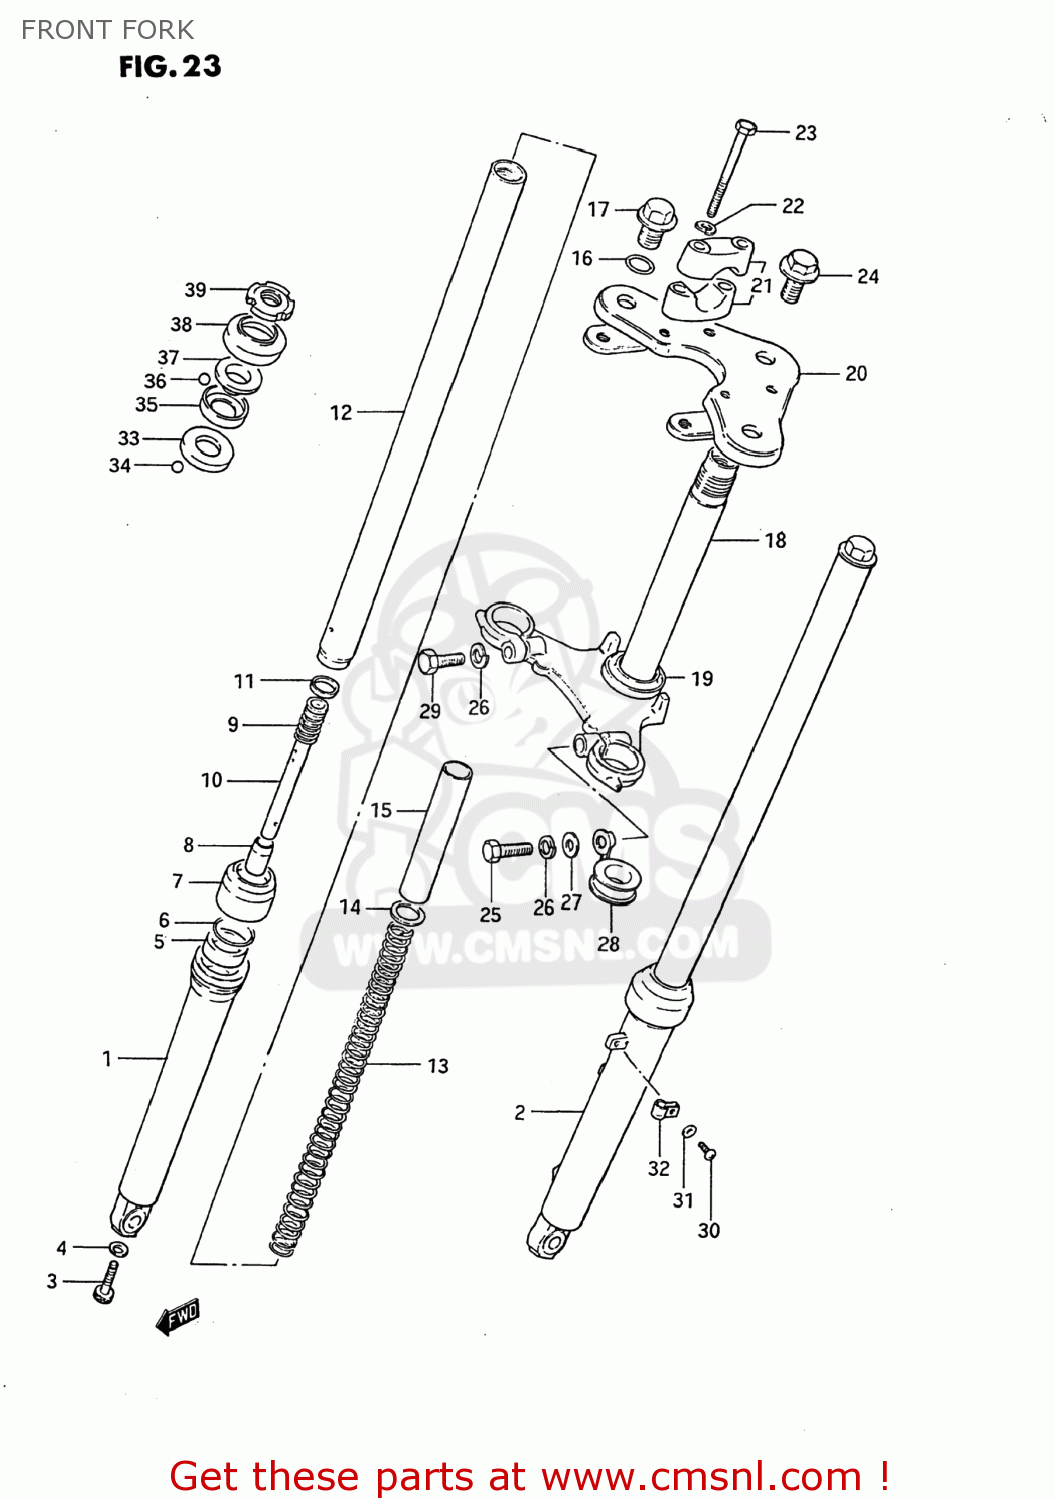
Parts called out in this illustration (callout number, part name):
1	TUBE,OUTER,RIGHT
2	TUBE,OUTER,LEFT
3	BOLT(8X27)
4	GASKET (NAS)
5	SEAL,OIL
6	RING,OIL SEAL STOPPER
7	DUST SEAL
8	PIECE,OIL LOCK
9	SPRING,REBOUND
10	CYLINDER,FR FORK
11	RING,PISTON
12	TUBE,INNER
13	SPRING
14	JOINT,SPRING
15	SPACER,SPRING
16	O-RING,FORK INNER TUBE
17	CAP
18	STEM,STEERING
19	RACE,STEERING OUTER LWR
20	HEAD,STEERING STEM
21	HOLDER,HANDLEBAR
22	WASHER,LOCK
23	BOLT
24	BOLT
25	BOLT,M10X1.25X
26	WASHER,LOCK
27	WASHER
28	CLIP
29	BOLT 10X30
30	SCREW
31	WASHER,LOCK 4M
32	CLIP,CABLE
33	LACE,STEERING INNER LWR
34	BALL
35	RACE,STEERING INNER UPR
36	BALL
37	RACE,STEERING OUTER UPR
38	DUST SEAL,STEERING UPR
39	NUT,STEERING STEM(25X44X10)
